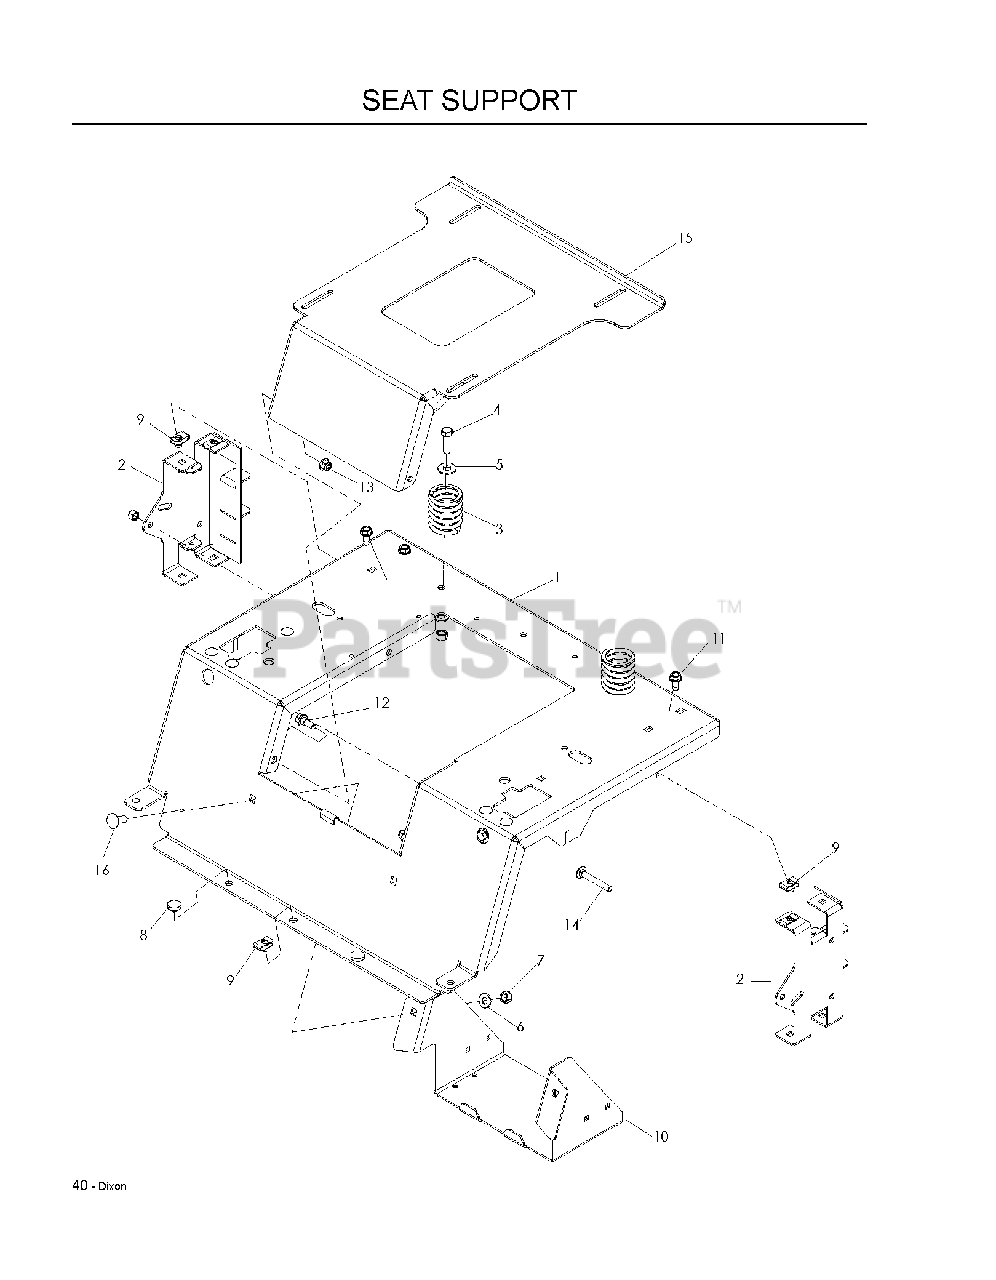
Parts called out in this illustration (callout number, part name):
1	SUPPORT, SEAT, BLUE
2	SUPPORT, REAR SEAT, BLACK
3	SPRING, SEAT
4	HCS 3/8C X 1 1/4 GR5
5	WASHER 3/8 FLAT
6	WASHER 3/8 SAE FLAT
7	NUT 3/8-16 NYLOC
8	GROMMET, BUMPER
9	U-CLIP 5/16-18 NUT RETAINER
10	BOX, BATTERY, BLACK
11	BOLT 5/16-18 X 3/4
12	SB 5/16-18 HEX HD GD5, BLK ZN
13	5/16-18 NYLOC FLANGE NUT
14	RHSNB 5/16-18 X 2-1/2 GR5 ZD
15	PAN, SEAT, BLUE
16	RHSNB 3/8C X 1
